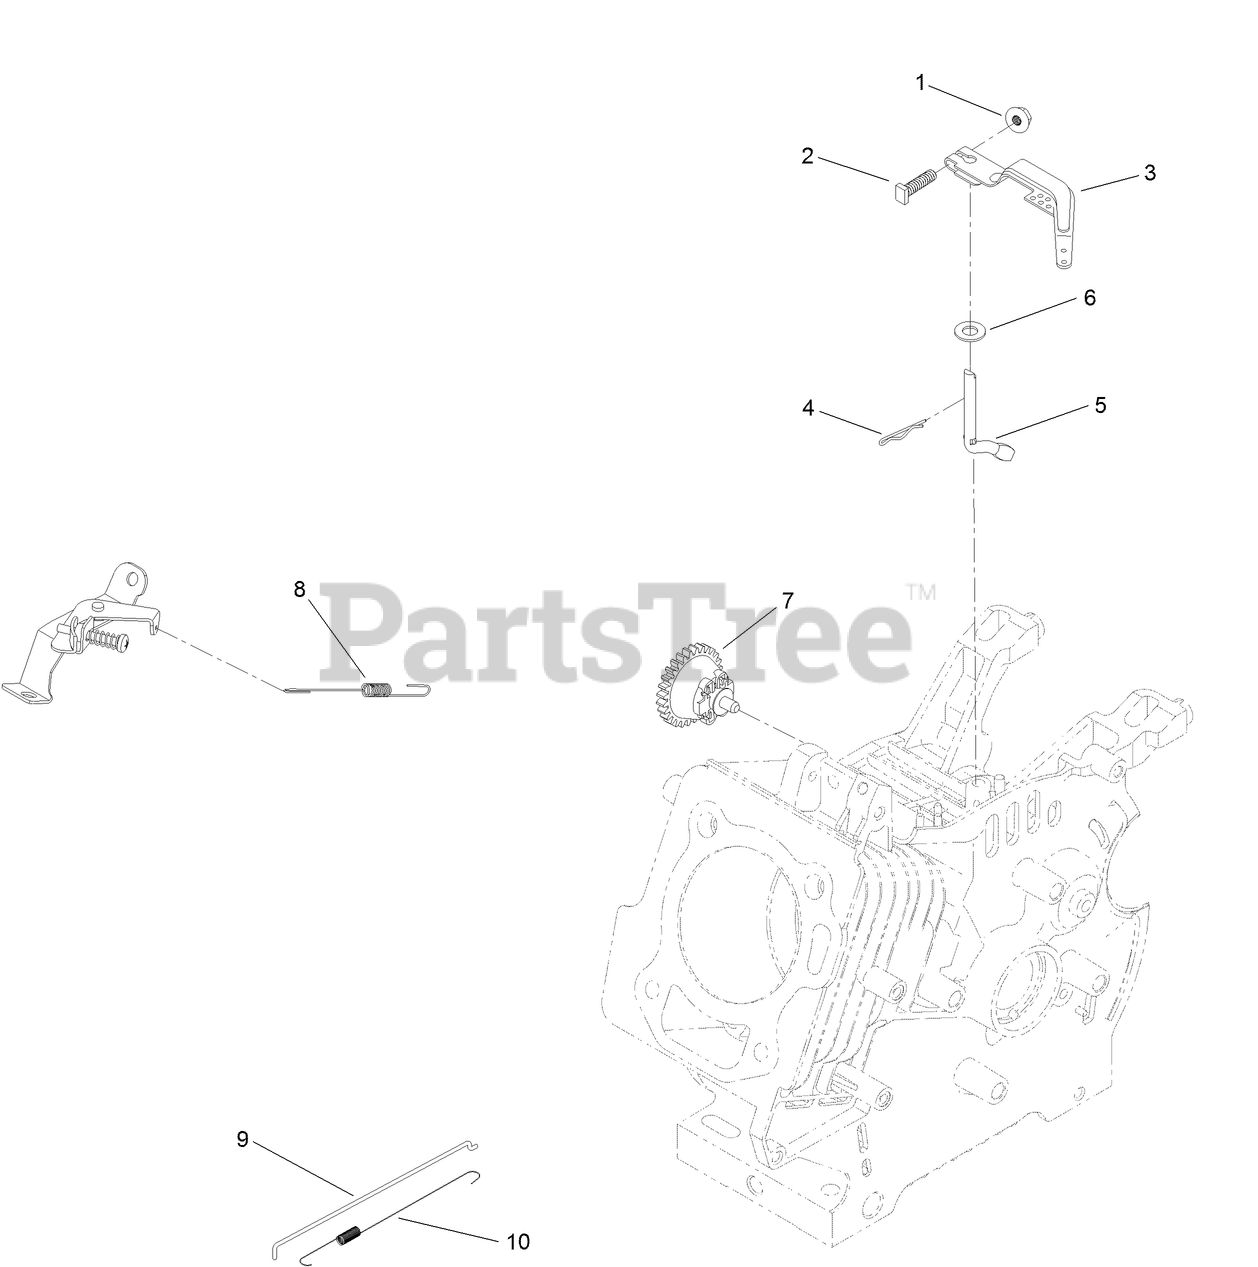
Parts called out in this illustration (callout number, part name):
1	NUT-FLANGE
2	BOLT-ARM, GOVERNOR
3	ARM-GOVERNOR
4	PIN-HAIR
5	SHAFT-GOVERNOR
6	WASHER-PLAIN
7	GOVERNOR GEAR ASM
8	SPRING-GOVERNOR
9	ROD-GOVERNOR
10	SPRING-RETURN, THROTTLE
